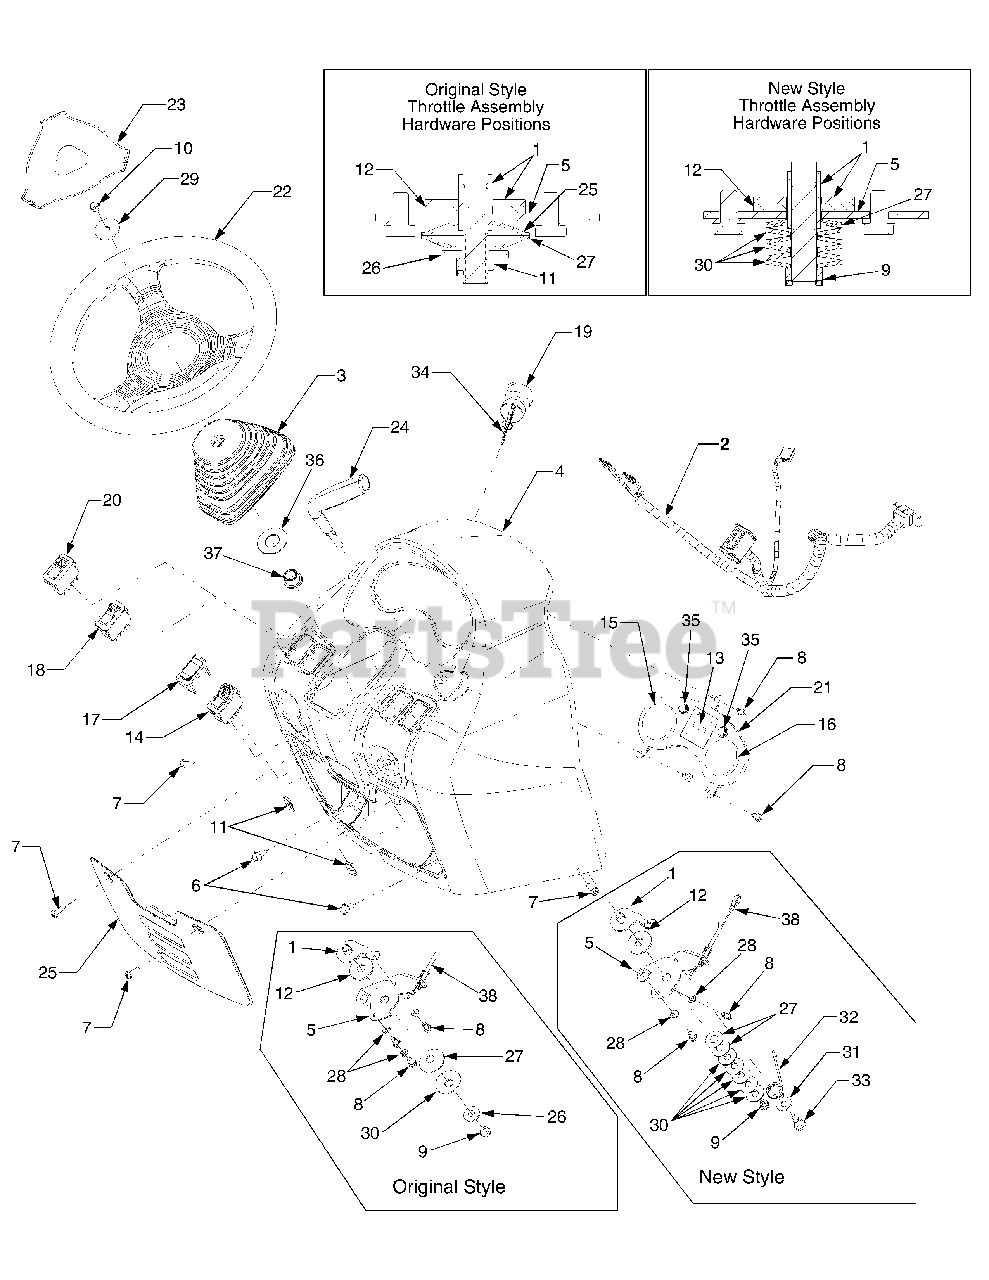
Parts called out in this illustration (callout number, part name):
2	Wire Harness, Dash
3	Boot, Steering Shaft
4	Dash
5	Bracket, Throttle Mounting
6	Screw, Hex Wash. Hd. Tapp 5/16-18 x .625
7	Screw, Pan Hd., 1/4-20 x .75
8	Screw, Hex Cap, 1/4-20 x .5 GR5
9	Nut, Hex Insert Jam Lock, 3/8-24 ..
10	Nut, Hex Lock, 5/16-24
11	Nut, Speed, 1/4-20
12	Washer, Friction, .515 x 1.5 x .12
13	Meter, Hour/Indicator
14	Switch, PTO
15	Gauge, Fuel
16	Gauge, RPM
18	Switch, Headlight
19	Switch, Ignition
20	Switch, Hazard
21	Panel, Meter
22	Steering Wheel, Soft Grip
23	Cover, Steering Wheel
24	Handle, Throttle
25	Panel, Dash Insert
26	Washer, Flat, .406 x 1.0 x .105
27	Washer, Belleville, .531 x 1.62 x .045
27	Washer, Belleville, .51 x 1.14 x .04
28	Washer, Lock, 1/4
29	Washer, Flat, .344 x 1.5 x .1
30	Washer, Spher., .39 x 1.62 x .045
30	Washer, Belleville, .39 x 1.13 x .062
31	Washer, Flat, .38 x .93 x .110 Hdn
32	Spring, Torsion
33	Screw, Shoulder, .374 x .56
34	Key Set, Ingition
35	Lamp, Yellow Panel - Original Style
35	Lamp, Yellow Panel - New Style
36	Washer, Flat, .885 x1.85 x .06
37	Bearing, Flange, .63 ID x .62 LG
38	Cable, Throttle
